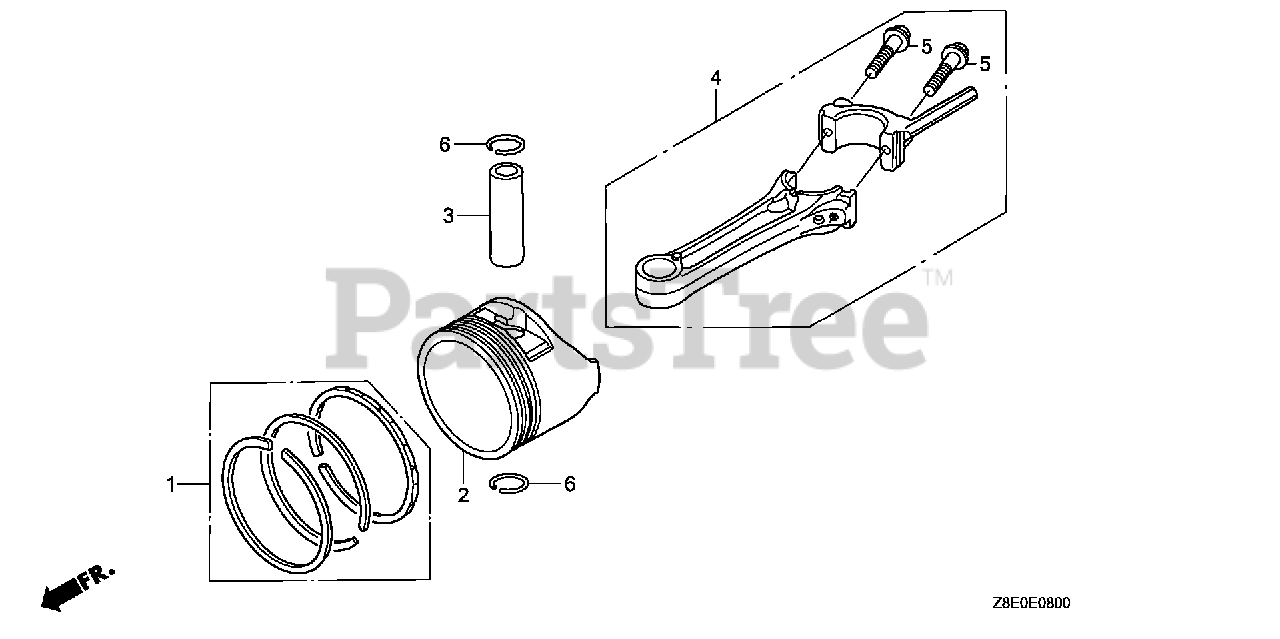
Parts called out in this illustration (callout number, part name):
1	RING SET, PISTON (STD) (TEIKOKU)
2	PISTON
3	PIN, PISTON
4	ROD ASSY., CONNECTING
5	BOLT, CONNECTING ROD
6	CLIP, PISTON PIN (13MM)
